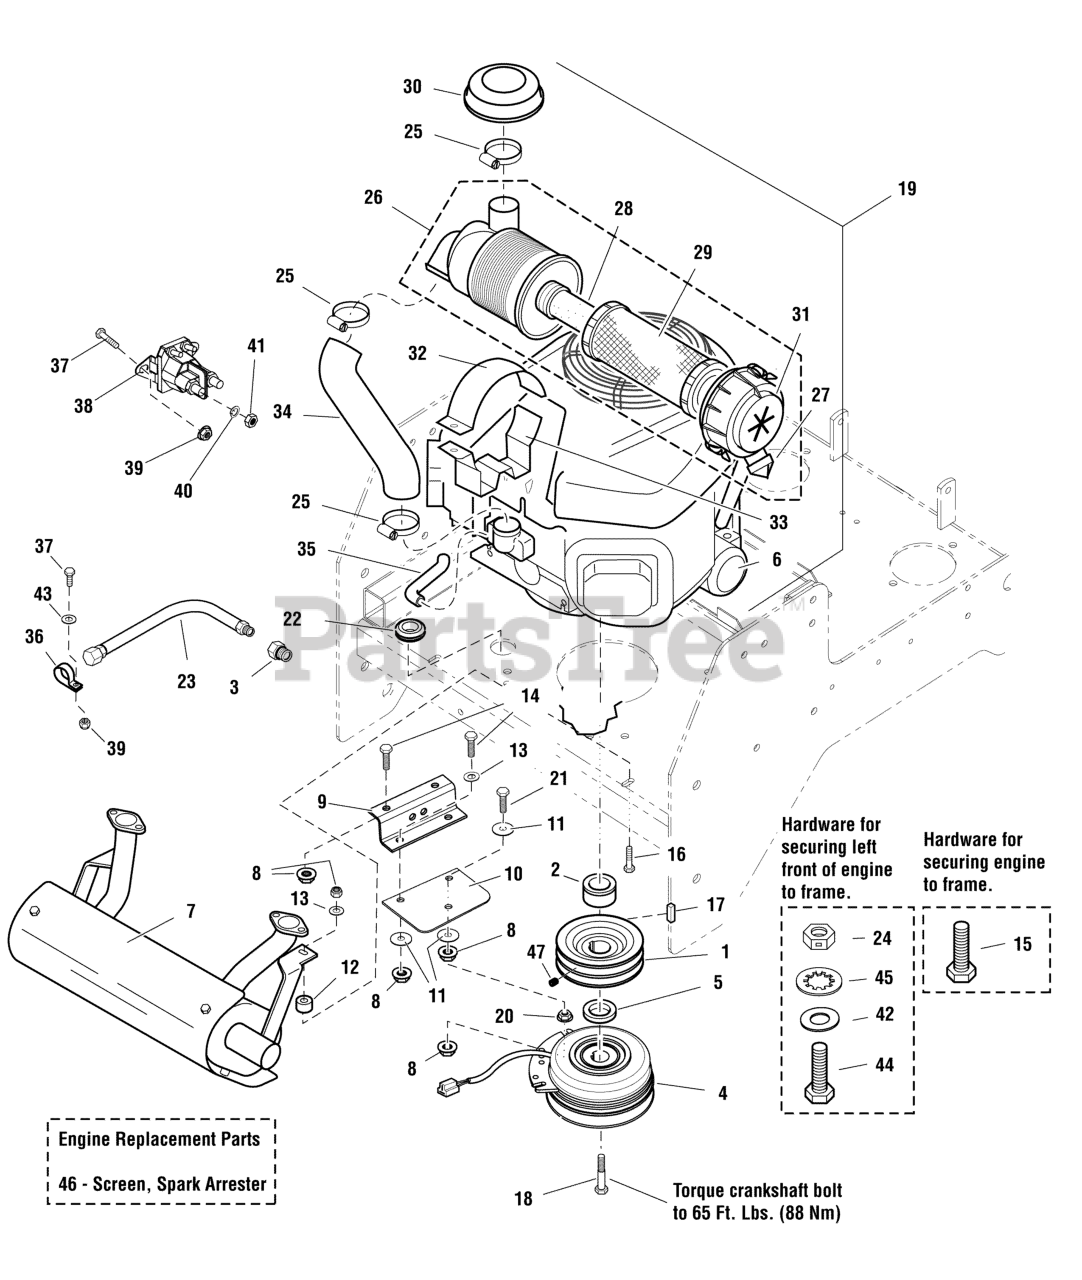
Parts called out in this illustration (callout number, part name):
1	PULLEY, CRANKSHAFT, 1.126 ID X 4.75 OD
2	SPACER, 1.13 X 1.75 X 1.03, CZ
3	ADAPTER, Oil Drain
4	CLUTCH WARNER 200 FT-LB 1.13 X 6.323
5	SPACER, 1.13 X 1.75 X .375
6	FILTER,OIL,KAWA FX751,801,851,921,100
7	MUFFLER 35-37HP KAWASAKI 5 CAN
8	NUT, 5/16-18 HEX NYLOCK FLANGE NUT
9	ANCHOR, CLUTCH - BLK
10	CLUTCH ANCHOR PAD
11	WASHER, .34 X 1.25 X 10 GA
12	SPACER, .39 X 1.00 X .80, CZ
13	WASHER, 5/16" SAE
14	BOLT, 5/16-18 X 1" GRD5 YZ
15	BOLT, HEX FLG, SER, GD5 3/8-16 X 1-1/4" PACH CZ
16	BOLT, 5/16-18 X 1-3/4" GD5 YZ
17	KEY, 1/4 SQ X 1
18	BOLT, CRANKSHAFT, 7/16" X 2-1/2"
19	ENGINE, 34HP, KAWASAKI
20	NUT, 5/16-18 HEX SERRATED FLANGE (LARGE)
21	BOLT, 5/16-18 X 2-1/4 TFL, GD5 YZ
22	GROMMET, 7/8"
23	HOSE, OIL DRAIN
24	NUT, Hex, Side Lock, 3/8-16
25	CLAMP, HOSE
25	CLAMP, CAP
26	AIR FILTER ASSEMBLY, 22,24&26HP KAWASAKI (SV)
26	AIR FILTER ASSEMBLY (SV)
27	RUBBER, Dust Valve, 22,24&26HP KAWASAKI (SV)
27	RUBBER, Dust Valve (SV)
28	AIR FILTER, SECONDARY, 22, 24&26HP KAWASAKI (SV)
28	AIR FILTER, ELEMENT, SECONDARY
29	AIR FILTER, PRIMARY,22,24&26HP, KAWASAKI (SV)
29	AIR FILTER, ELEMENT, PRIMARY
30	RAIN CAP, AIR FILTER, 22,24&26HP, KAWASAKI (SV)
30	RAIN CAP, KAWA, DFI
31	CAP END, FILTER CASE, 22,24&26HP, KAWASAKI (SV)
31	CAP END, FILTER CASE (SV)
32	BRACKET PLATE, UPPER, 22,24&26HP KAWASAKI (SV)
32	BRACKET PLATE, UPPER 27, 34 & 37 (SV)
33	BRACKET PLATE, LOWER, 22,24&26HP KAWASAKI (SV)
33	BRACKET PLATE, LOWER 34 & 37 (SV)
34	AIR INLET TUBE, 22,24&26HP KAWASAKI (SV)
34	AIR INLET TUBE (SV)
35	AIR INLET TUBE,AIR FILTR,22,24&26HP KAWA
35	BREATHER TUBE (SV)
36	CLAMP, VINYL INSULATED, 1.00
37	BOLT, 1/4"-20 X 3/4" GD5 YZ
38	SOLENOID-4 POLE 12 VOLT DC (TROMBETTA)
39	NUT, 1/4-20 HEX SERR. FLANGE
40	WASHER, Light Lock, 5/16
41	NUT, Hex Jam, 5/16-24
42	WASHER, 3/8 SAE
43	WASHER, 1/4 SAE
44	BOLT, 3/8-16 X 2-1/4" GD5 TFL
45	WASHER, 3/8" ID, INTERNAL TOOTH
47	SET SCREW, 5/16-18 X 3/8, KNURL, W/PATCH
